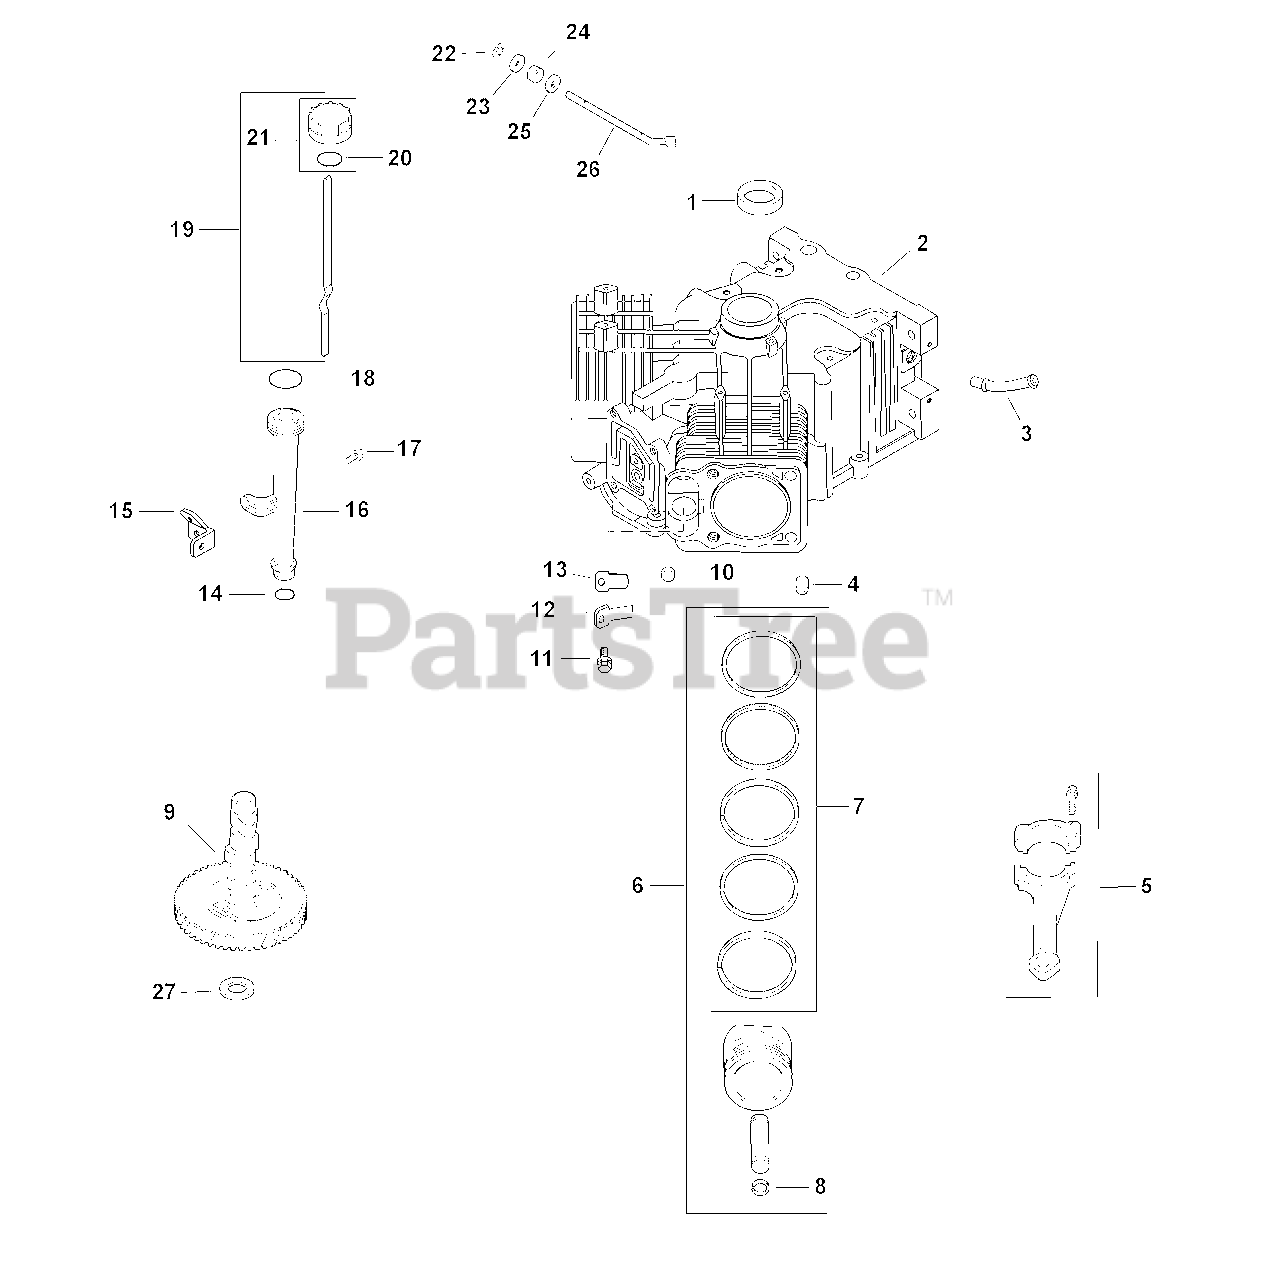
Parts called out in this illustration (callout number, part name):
2	Crankcase
5	Connecting Rod (STD)
5	Connecting Rod (.25)
6	Piston Kit w/ Ring (STD) (Inc. 7 & 8)
6	Piston Kit w/ Ring (.08)
6	Piston Kit w/ Ring (.25)
6	Piston Kit w/ Ring (.50)
7	Piston Ring Set (STD)
7	Piston Ring Set (.08)
7	Piston Ring Set (.25)
7	Piston Ring Set (.50)
8	Piston Pin Retainer
9	Camshaft Kit
11	Flange Screw, M5 x 0.8 x 10
12	Breather Reed Retainer
13	Breather Reed
14	Lower Oil Fill Tube O-Ring
15	Oil Fill Tube Bracket
16	Oil Fill Assembly Tube
17	Flange Screw, M5 x 0.8 x 16
18	Upper Oil Fill Tube O-Ring
19	Dipstick Assembly (Inc. 20 & 21)
20	Dipstick O-Ring
21	Oil Fill Cap Kit (Yellow)
22	Ring Retainer
23	Flat Washer, 9 mm
24	Governor Cross Shaft Seal
25	Flat Washer, 1/4"
26	Governor Cross Shaft
27	Camshaft Shim (White .028")
